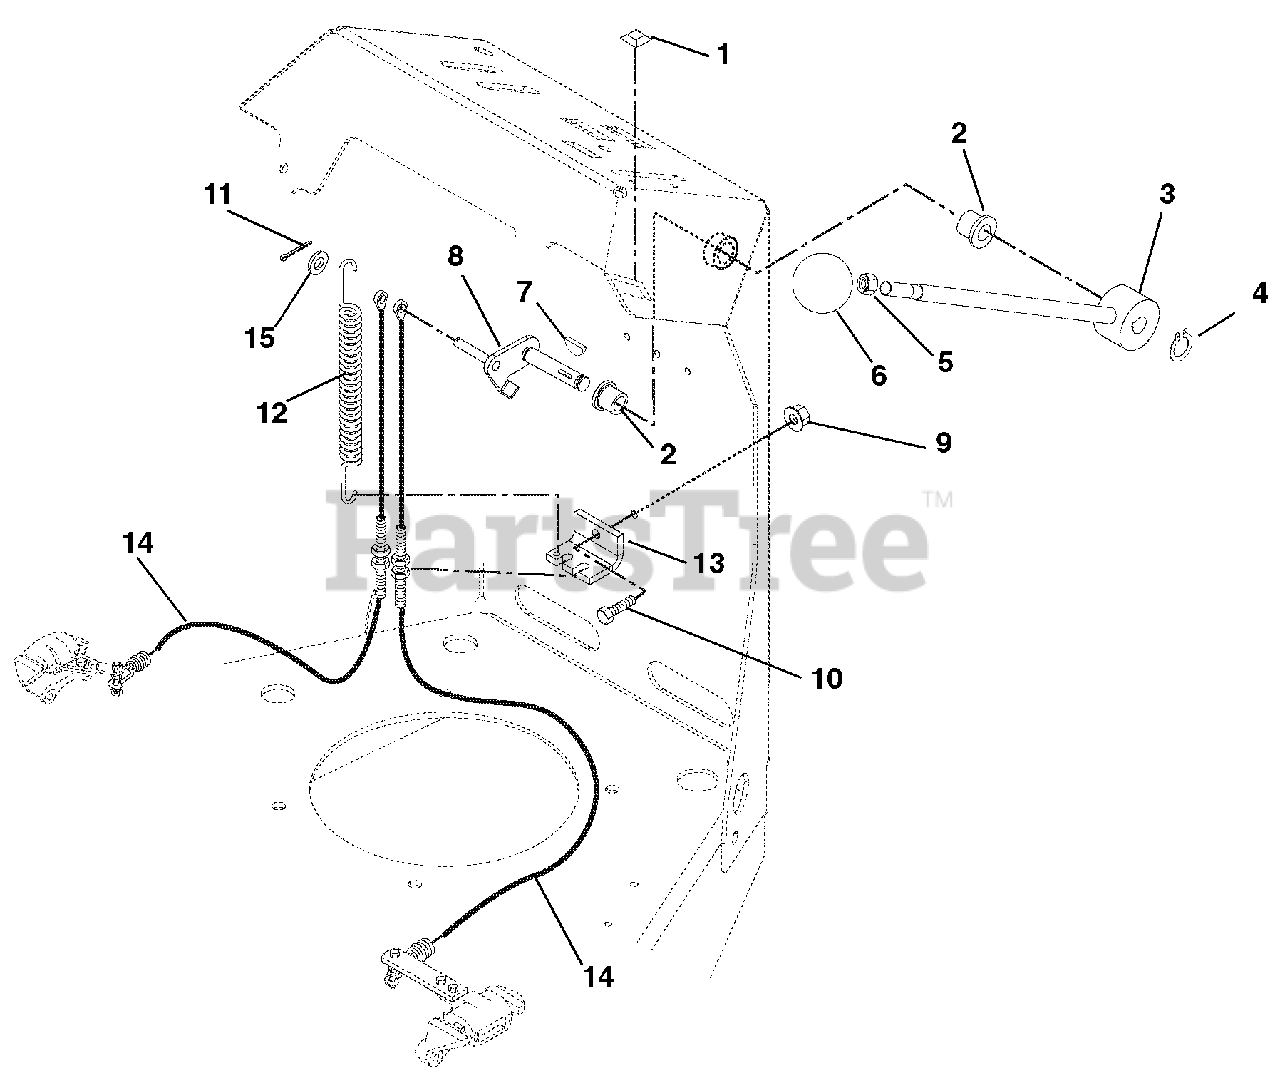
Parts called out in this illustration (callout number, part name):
2	Bushing-Flange .50 x .75 x .75 x 1.00
3	Weldment, Parking Brake Lever
4	Ring-Retaining-External .50 x .05
5	Nut-Hex-Jam .38-16
6	Knob-Steering Lock
7	Key-Woodruff .13 x .63
8	Weldment, Shaft Brake Activation
9	Nut-Locking-Top-Flange .31-18
10	Bolt-Hex .31-18 x 1.00 Grade 5
11	Pin-Cotter .09 x .75
12	Spring-Tension .062 x .56 x 8.0
13	Bracket, Cable
14	Cable, Parking Brake
15	Washer-Flat-Steel .344 x .688 x .065
